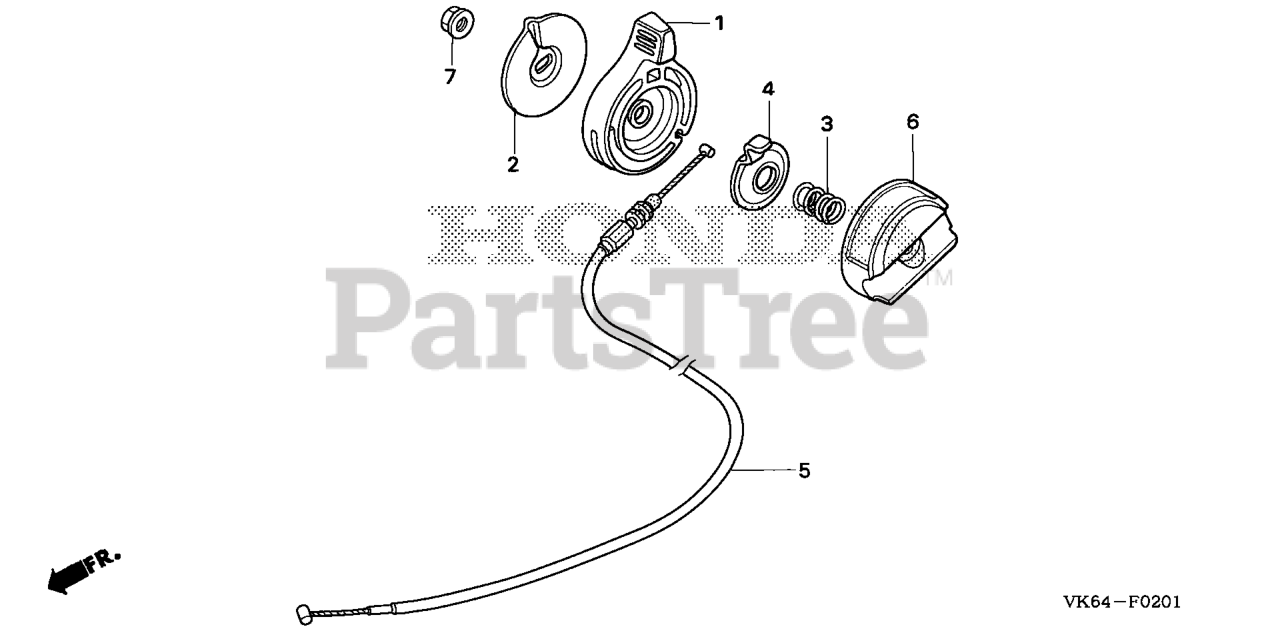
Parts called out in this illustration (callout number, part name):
1	LEVER, THROTTLE
2	PLATE, THROTTLE LEVER
3	SPRING, THROTTLE LEVER
4	SEAT, SPRING
5	CABLE, THROTTLE
6	COVER, CONTROL
7	NUT, FLANGE (6MM)
